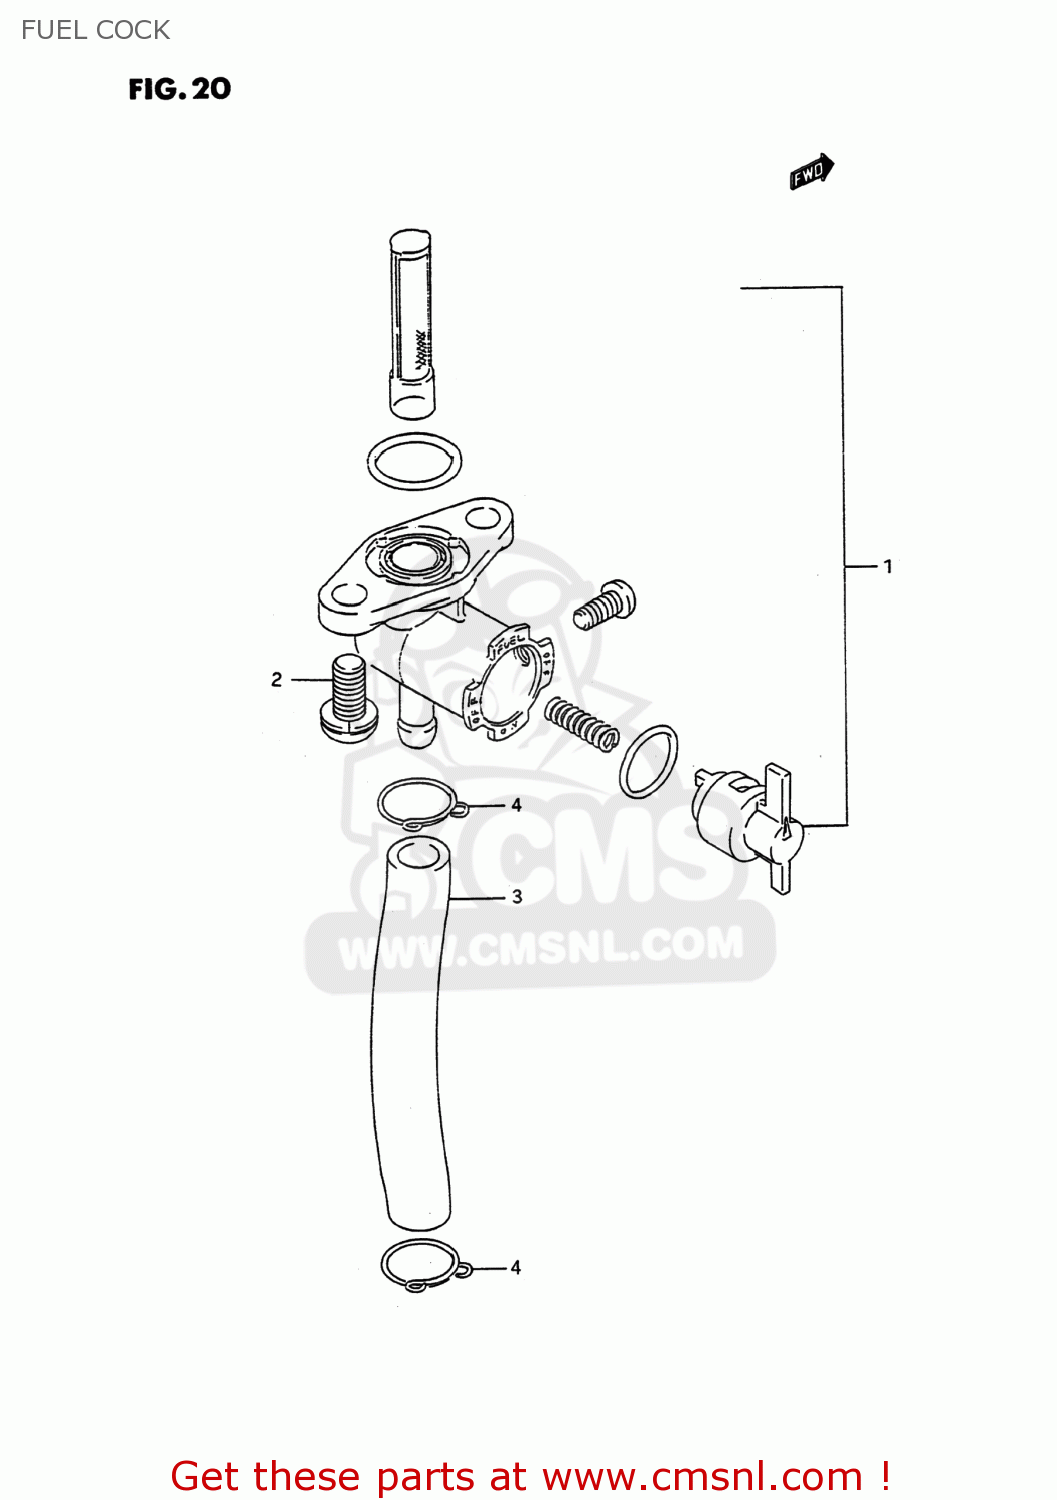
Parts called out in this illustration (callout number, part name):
1	COCK ASSEMBLY,FUEL
2	SCREW
3	HOSE(6.5X11.5X600)
4	CLIP
